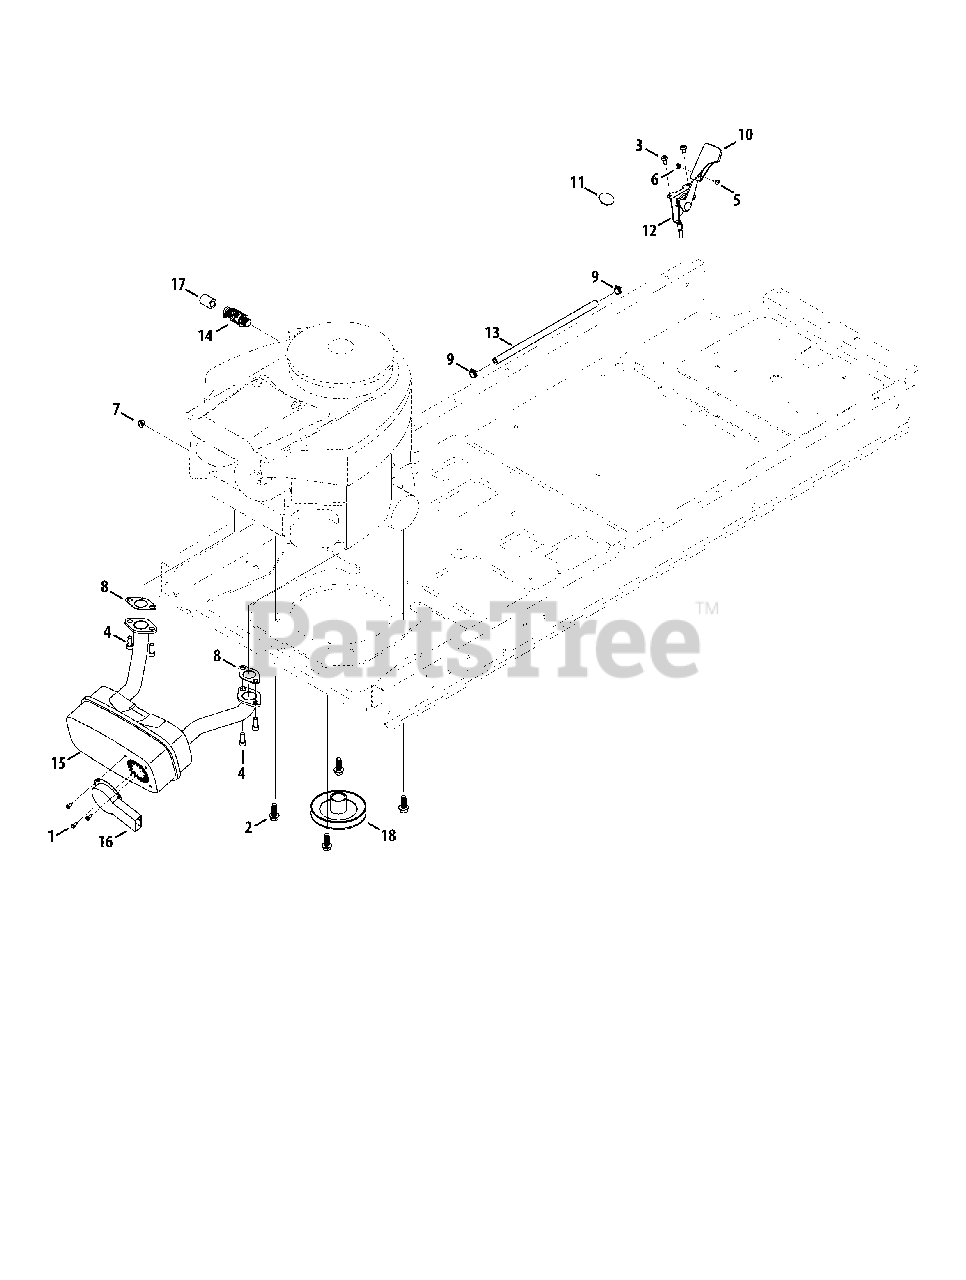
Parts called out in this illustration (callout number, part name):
1	SCREW, #8-18 X .500, Hex Washer
2	CAPSCREW, Hex Head, 3/8-16 x 1, GR5
3	SCREW, 1/4-20 X .50
4	SCREW, 5/16-18 X .750, Socket Head
5	SCREW, #8-32 X .375
6	NUT, #8-32, Hex
7	NUT, Nylock Flanged, 1/4-20
8	GASKET, Exhaust
9	CLAMP, .490 DIA., Hose
10	KNOB, Throttle Control
11	PLUG, Choke
12	CABLE, Throttle/Choke Control
13	HOSE, 1/4, Fuel
14	DRAIN, Oil
15	MUFFLER, Intek Twin
16	DEFLECTOR, Muffler, Long
17	HOSE, Oil Drain
18	PULLEY, Engine
